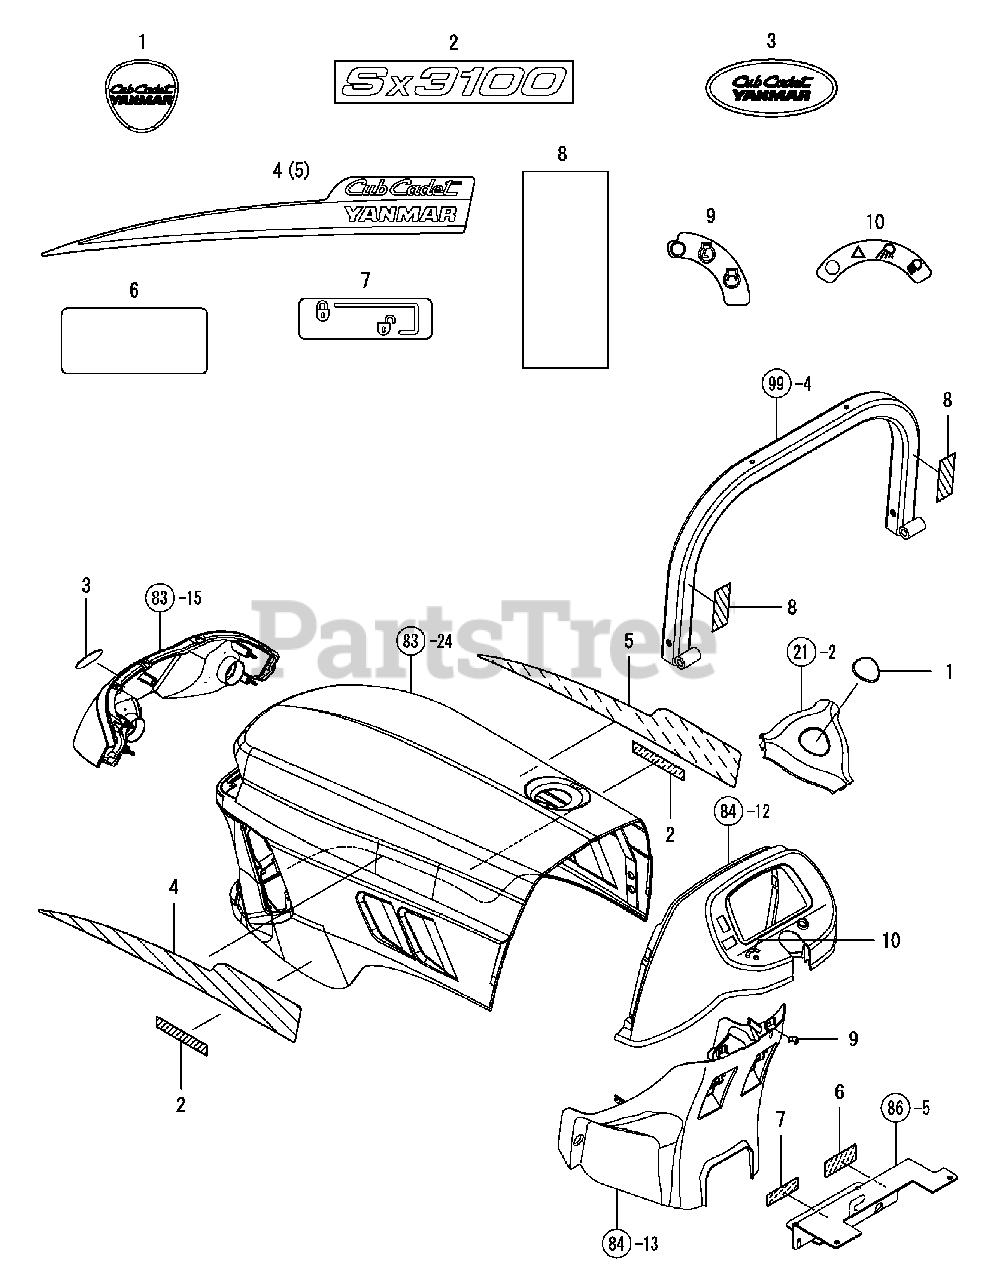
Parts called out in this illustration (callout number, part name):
1	Label,Steering Wheel
3	Label Center Logo
7	Decal, Scv Lock
8	Tape, Reflection
9	Label, Start Switch
